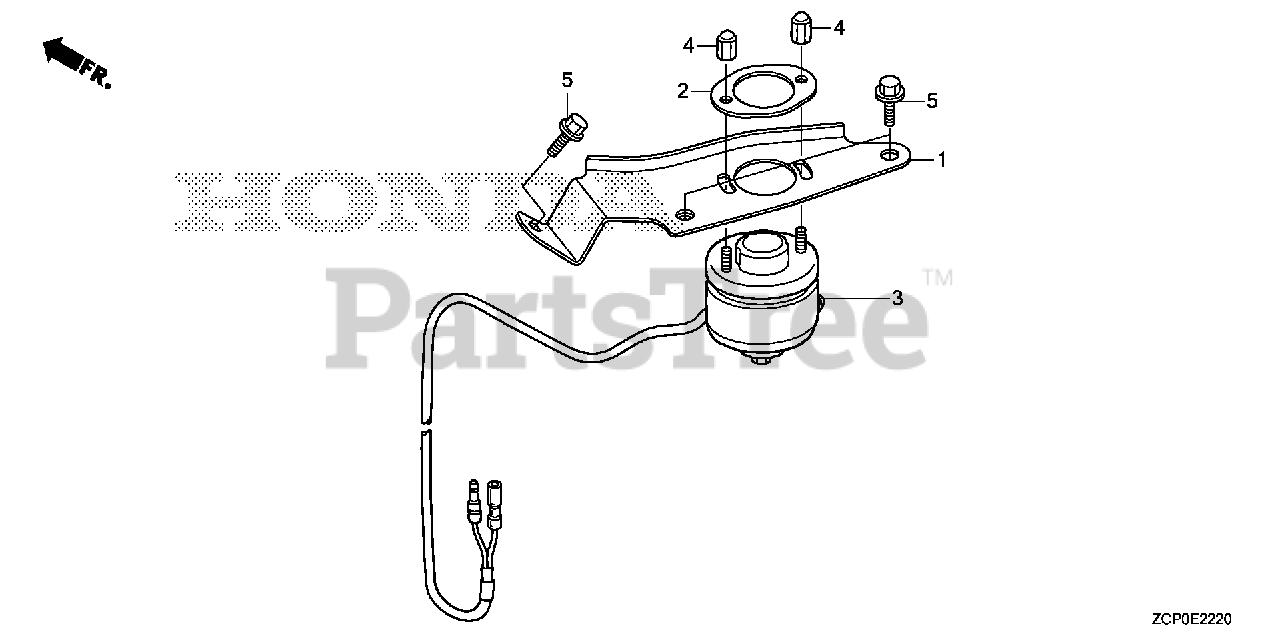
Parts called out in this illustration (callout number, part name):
1	STAY, SOLENOID
2	PLATE, SOLENOID
3	SOLENOID ASSY., ROTARY
4	NUT, SPECIAL CAP
5	BOLT, FLANGE (6X14)
